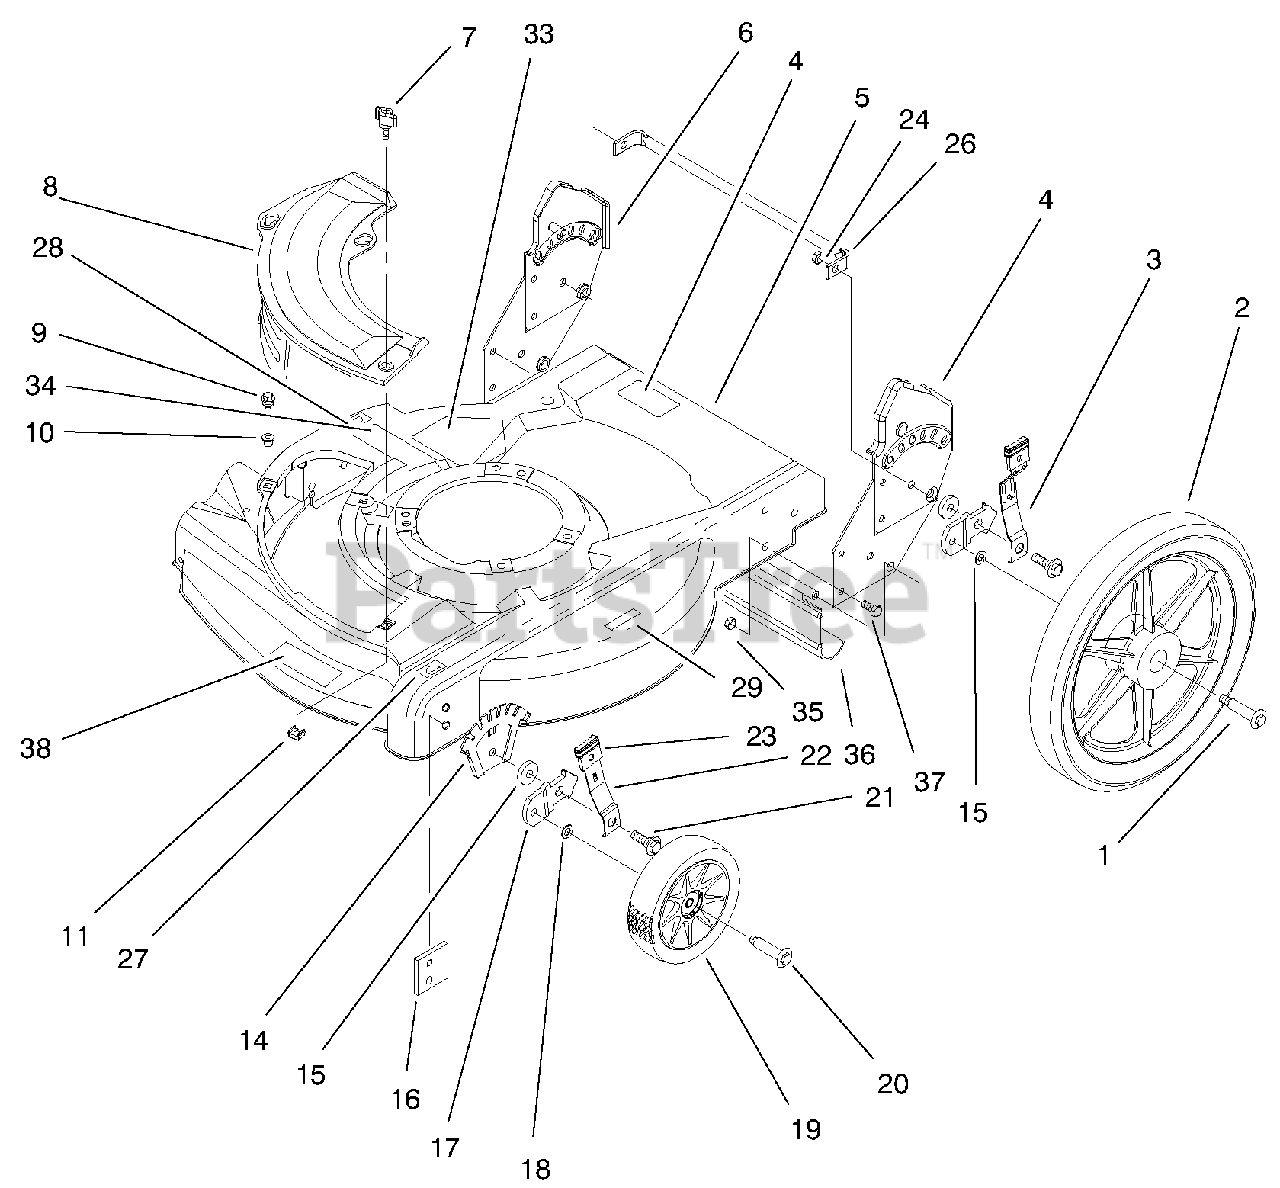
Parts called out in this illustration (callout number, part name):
1	Shoulder Bolt
2	Wheel-14 Inch
3	Assy-Spring Arm
4	Assy-Bracket Handle,LH
5	Asm-Housing/Baffle HP
6	Assy-Bracket Handle,Rh
8	Plate-Mulch
9	Screw-Sems
10	Grommet-Plastic
11	Nut-Cage
14	Plate-Hght Adj
15	Washer-Wheel
16	Plate-Baffle
17	Brkt-Whl Ht Adj
18	Washer-Wheel Bolt
19	6" Wheel & Tire ASM
20	Bolt-Shoulder 6" Wheel
21	Bolt-Shoulder
22	Arm-Front Spring
23	Knob-Height Adj Lever
24	Nut-Lock Ni
26	Brace-Handle Bracket
27	Decal-HOC L
28	Decal-HOC R
29	Decal-Safety Instruct
33	Decal-Danger
34	Decal-Warning
35	Nut-Lock Ni
36	Shield-Trailing
37	Screw-HH
38	Decal-Deck
